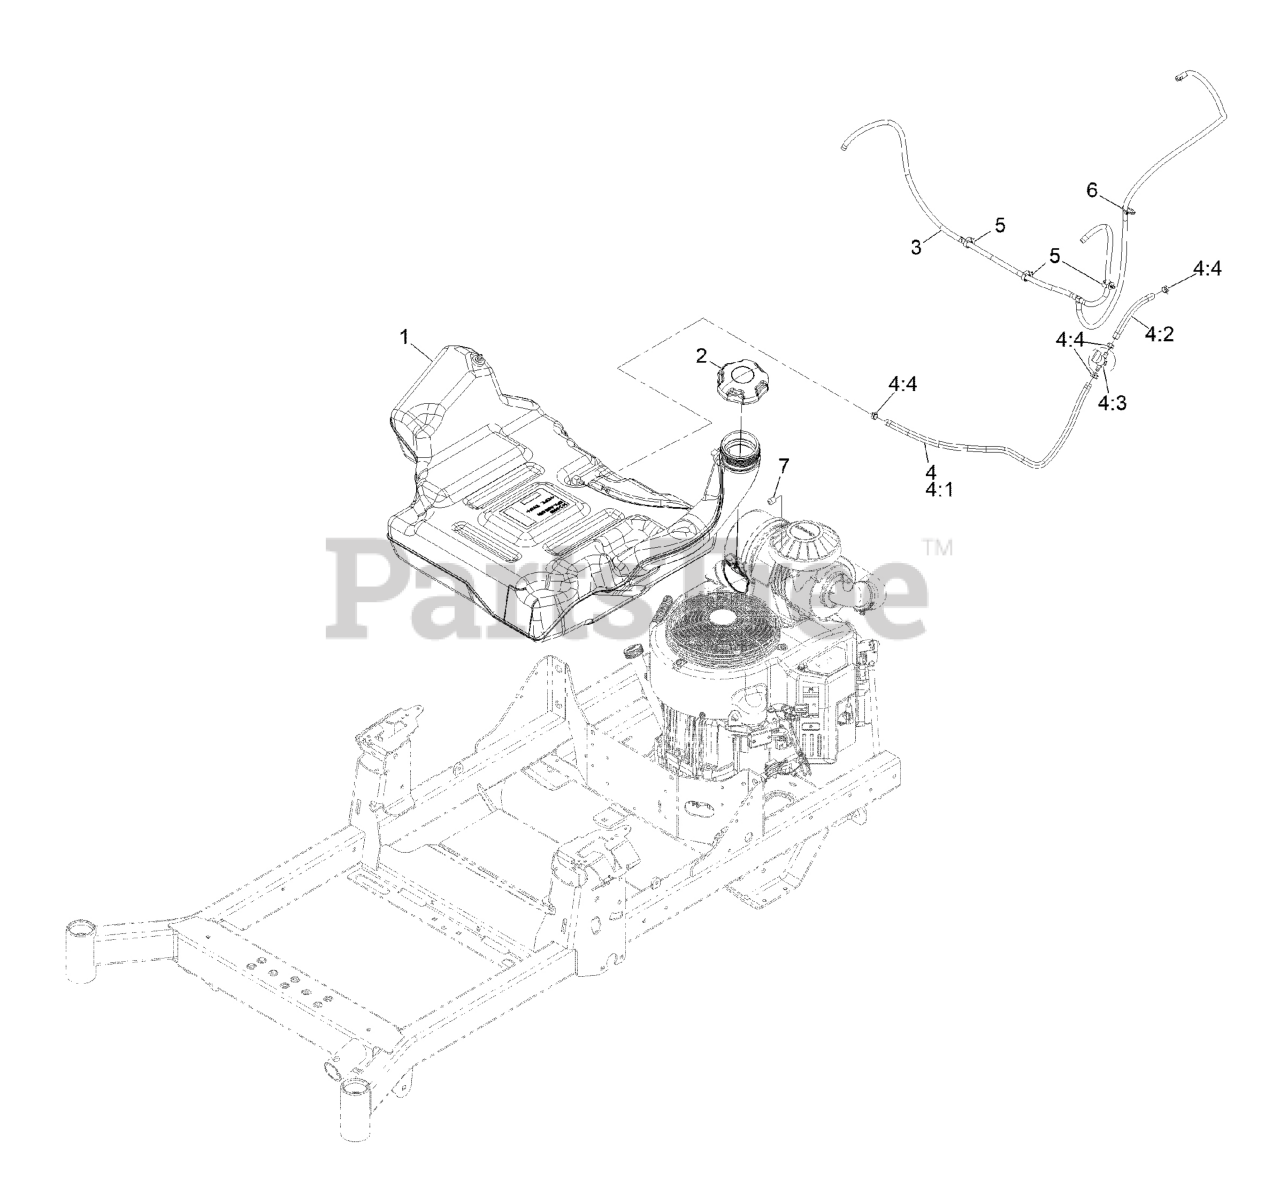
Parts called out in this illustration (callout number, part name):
1	ASM-FUEL TANK
2	CAP-FUEL, RATCHETING
3	Vent Hose ASM
4	FUEL HOSE ASM
4:1	HOSE-FUEL
4:2	HOSE-FUEL
4:3	VALVE-FUEL
4:4	CLAMP-HOSE
6	TIE-CABLE
7	PLUG-PORT
